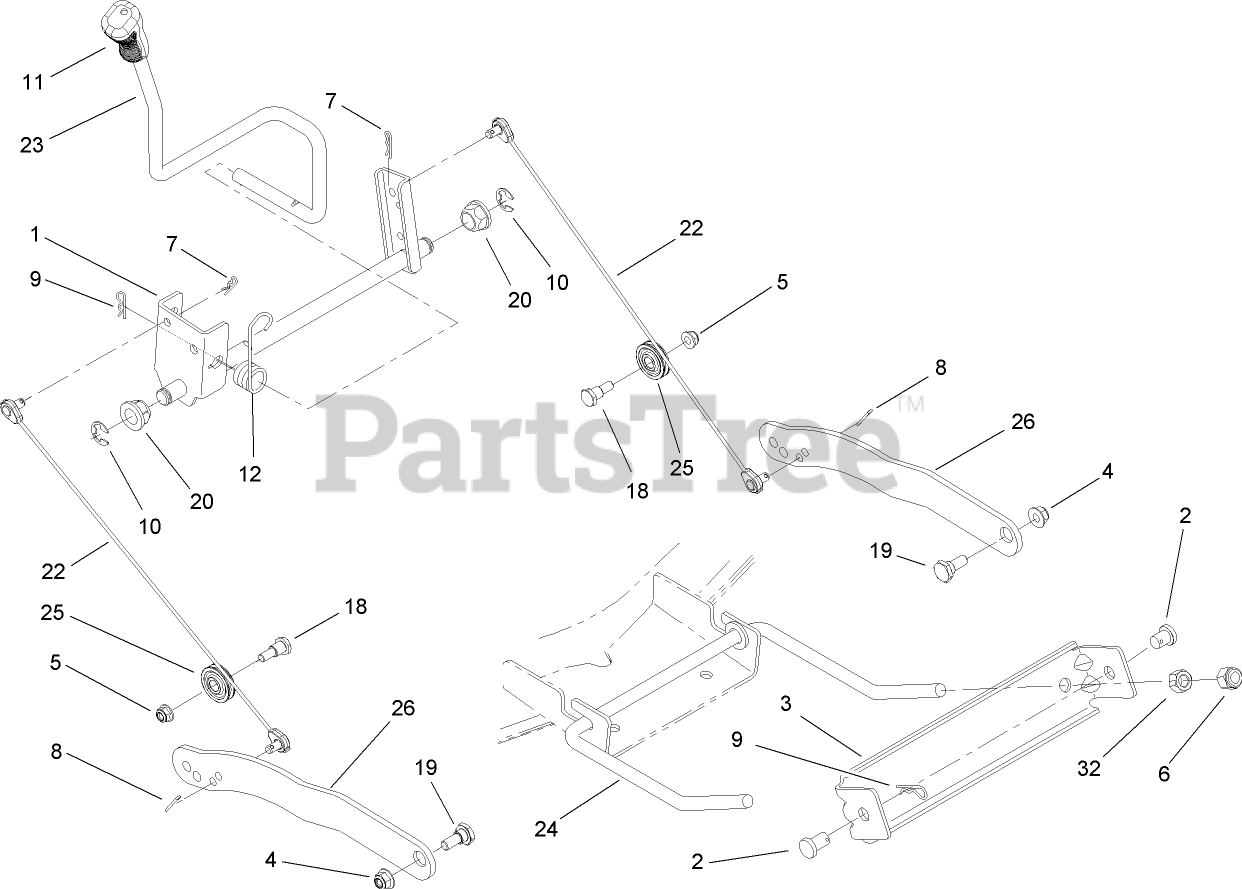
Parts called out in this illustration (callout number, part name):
1	LIFT SHAFT ASM
2	PIN-BRACKET, LIFT
3	BRACKET-STABILIZER
4	NUT-LOCK, FLANGE
5	NUT-LOCK, FLANGE
6	NUT-LOCK, HEX (NYLON)
7	PIN-COTTER
8	PIN-COTTER
9	PIN-HAIR
10	RING-E
11	GRIP-HANDLE
12	SPRING-TORSION
18	BOLT-SHOULDER
19	BOLT-SHOULDER
20	BEARING-FLANGE
22	CABLE-LIFT
23	HANDLE-LIFT
24	ROD-FRONT, ADJUST
25	PULLEY-ROLLER
26	LINK-LIFT
32	NUT-HEX
